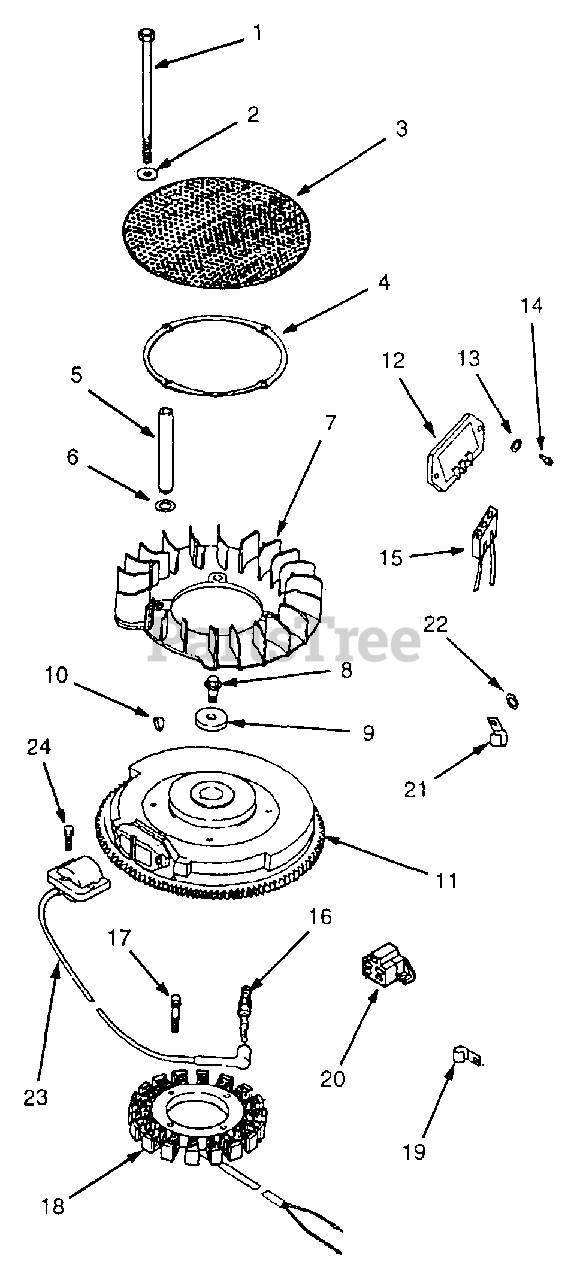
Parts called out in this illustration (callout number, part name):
1	Screw, Hex Cap, M6 x 1.0 x 100
2	Washer, .266 x .5
3	Screen, Grass
4	Ring, Support
5	Spacer, Grass Screen
6	Washer, Spring, 10mm
7	Fan
8	Screw, Hex Flange, M10 x 1.5 x 46
11	Flywheel
12	Rectifier/Regulator
13	Washer, 3/16
14	Screw, Phillips Hd, 11-16 x 7/8
15	Connector, Rectifier/Regulator
16	Spark Plug
17	Screw, Hex Cap, M5 x 0.8 x 25
18	Stator, 15 Amp
19	Clip, Cable
22	Washer, 1/4
23	Module, Ignition
24	Screw, Hex Flange, M5 x 0.8 x 20
